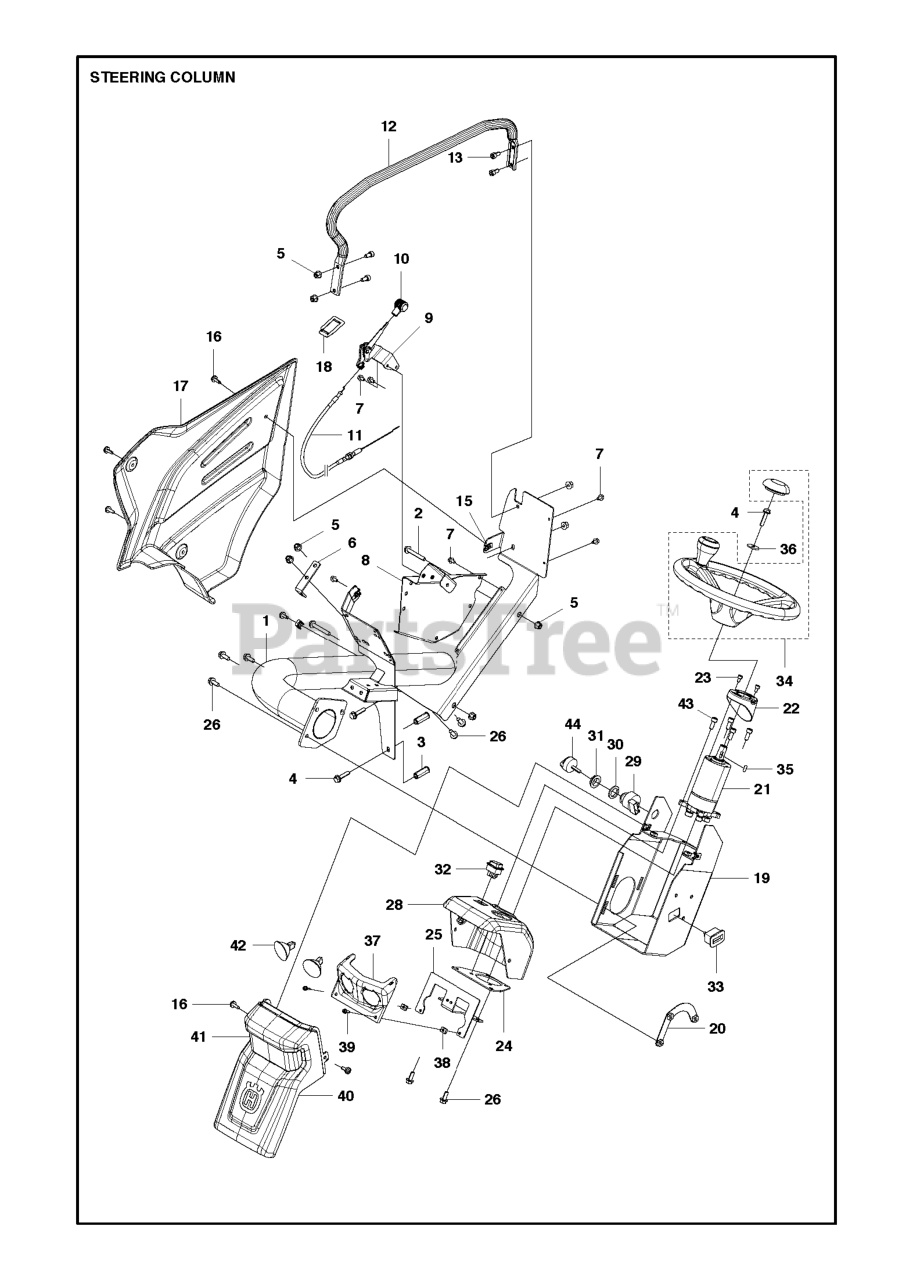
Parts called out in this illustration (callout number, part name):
2	SCREW EHHFM
4	SCREW EHHFM
5	NUT FLANGE
23	SCREW MC6S 6X10
